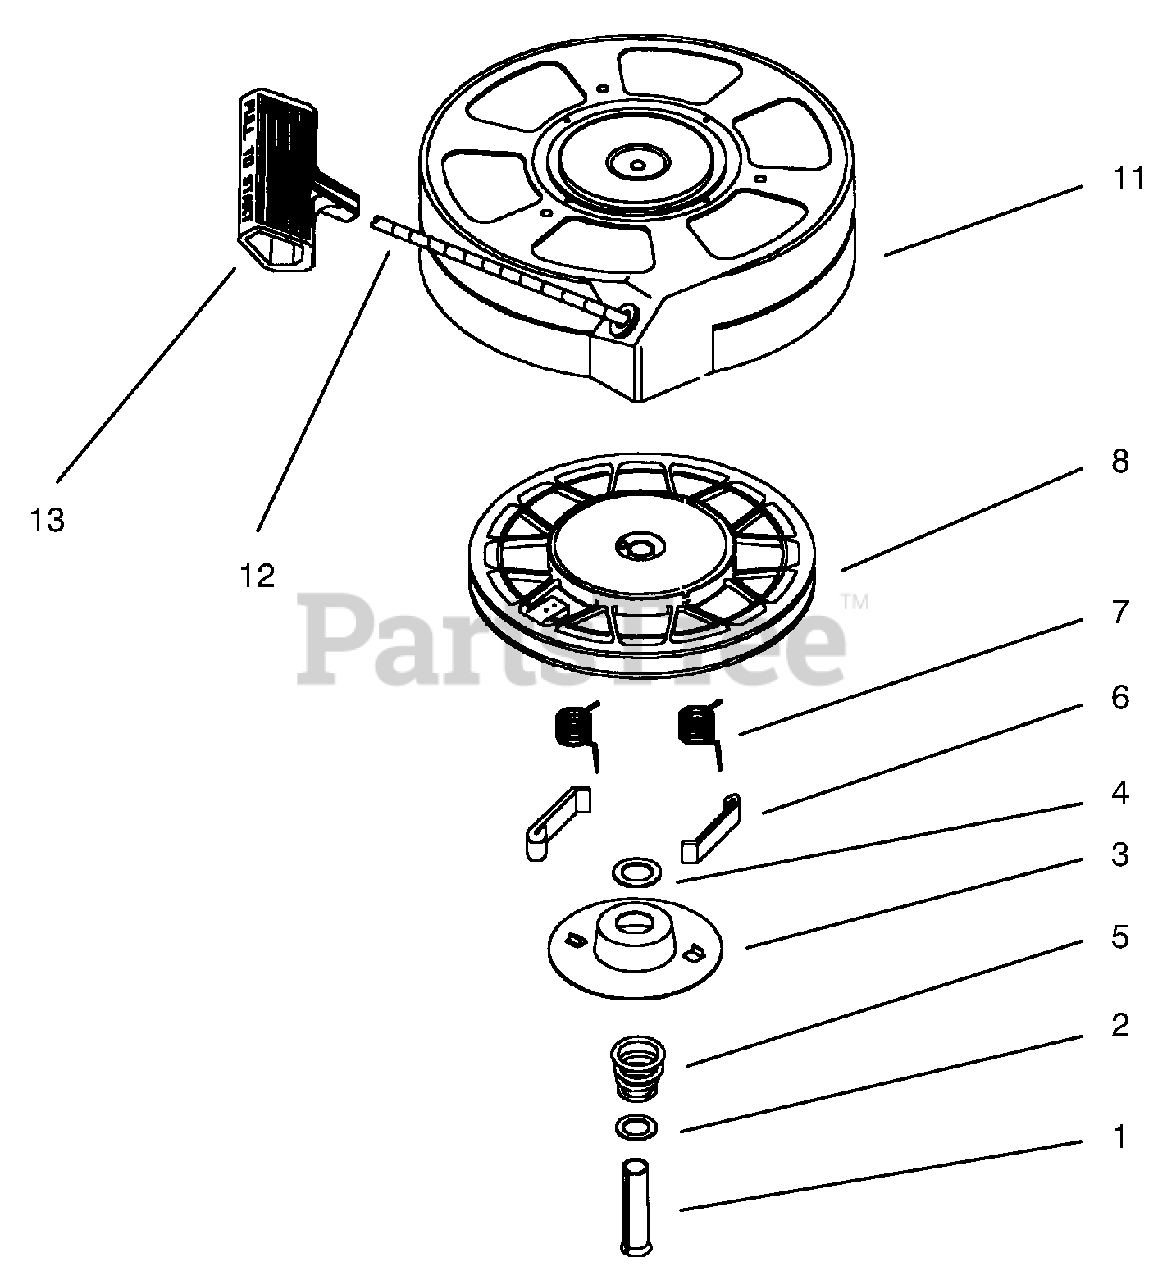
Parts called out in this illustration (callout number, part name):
1	Spring Pin (Incl. 4)
3	Retainer
5	Brake Spring
6	Starter Dog
7	Dog Spring
8	Pulley & Rewind Spring Ass'y.
11	Starter Housing Ass'y (40 degree grommet)
12	Starter Rope ( 98" X 9/64" dia.)
13	Starter Handle
